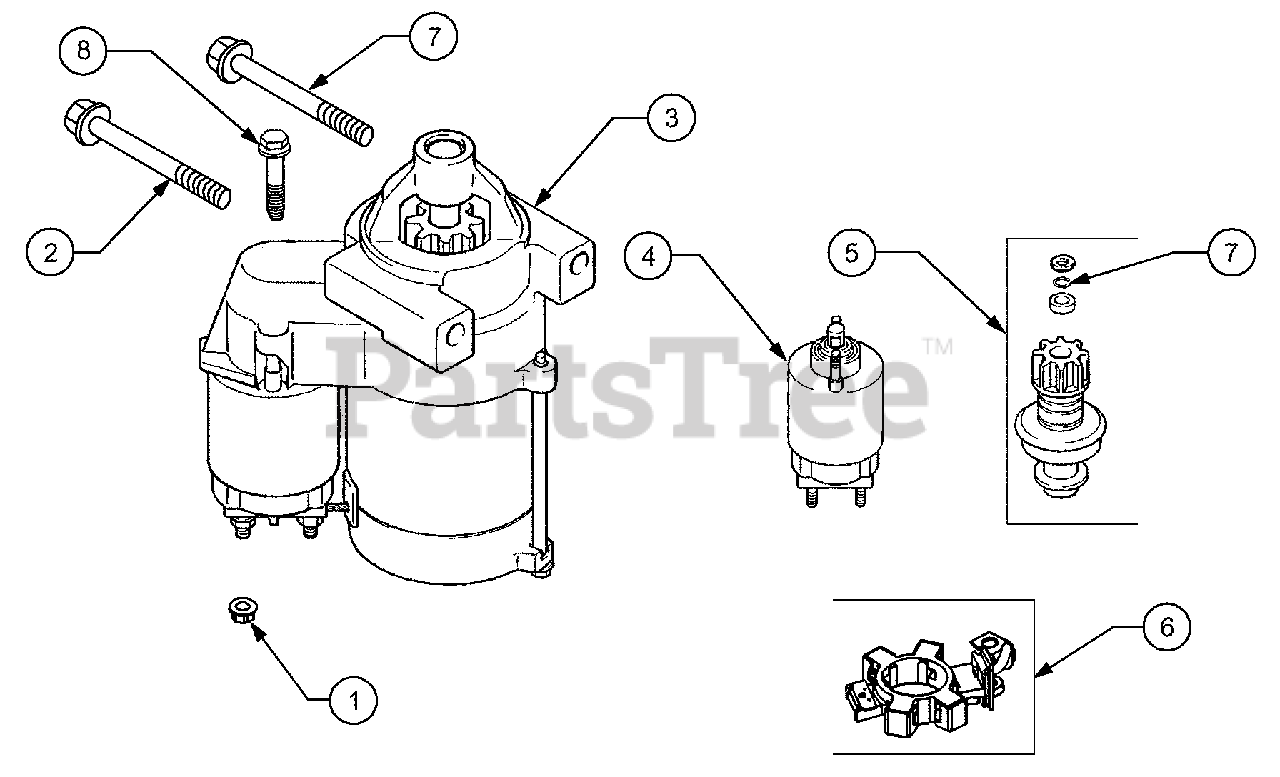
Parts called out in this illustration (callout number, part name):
1	Nut, Hex Flange M8 x 1.25"
2	Screw, Hex Flange M8 x 1.25 x 80
3	Starter, Solenoid Shift Assembly
4	Kit, Solenoid
5	Kit, Pinion Drive
7	Ring, Retainer
8	Screw, External Torx Hd.
